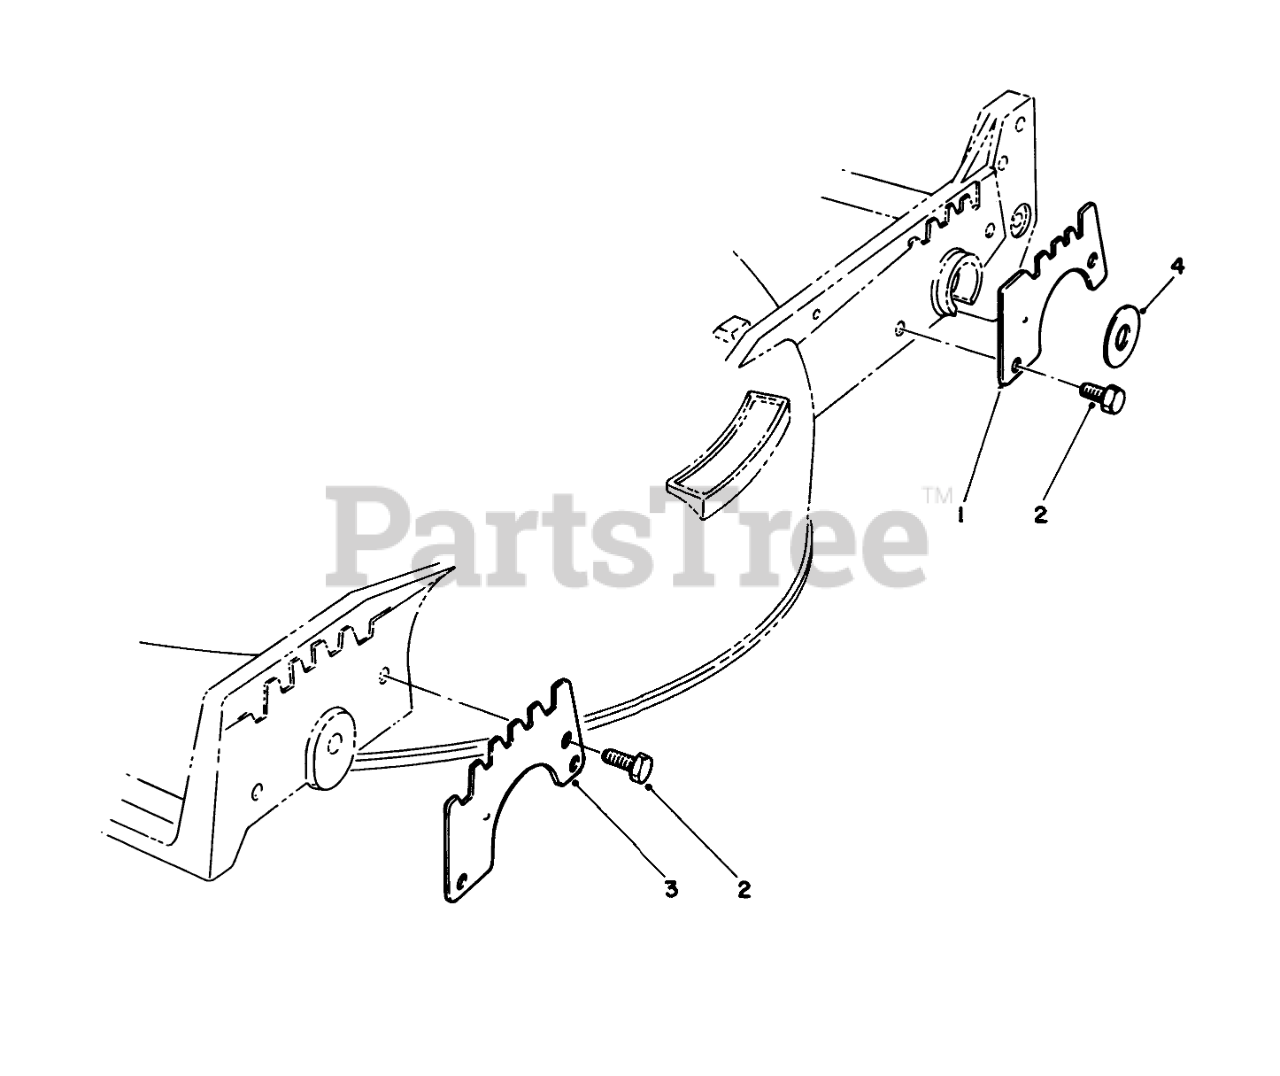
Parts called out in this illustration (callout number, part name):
1	WEAR PLATE,REAR
2	SCREW-HWH
3	WEAR PLATE
4	PIVOT WASHER
